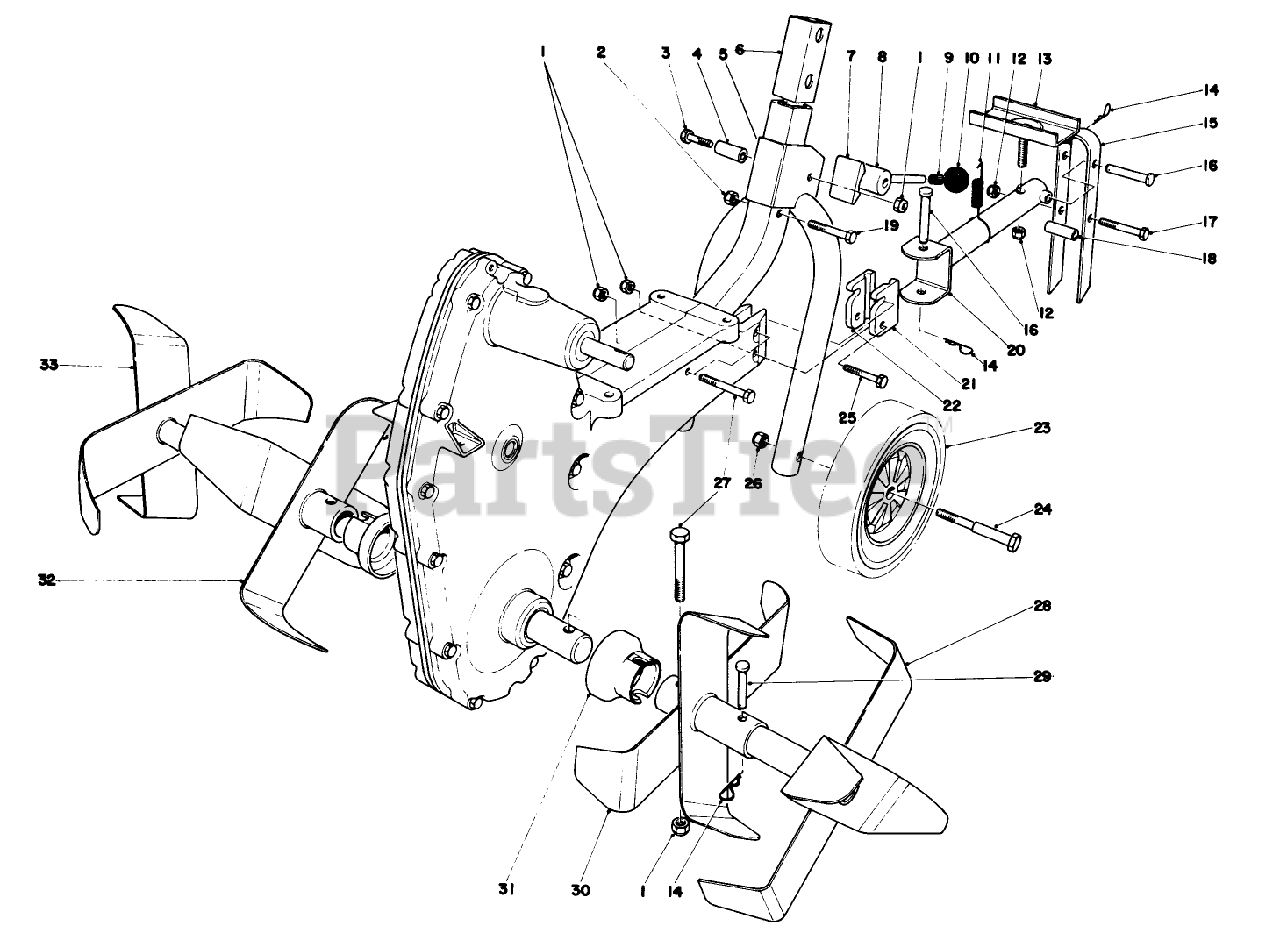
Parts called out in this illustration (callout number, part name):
1	NUT-HEX, SIDE DEFORM
2	NUT-HEX, SIDE DEFORM
3	SCREW-HH
4	CAM SPACER
12	NUT-LOCK, SIDE
14	PIN-COTTER
16	PIN-CLEVIS
17	SCREW-HH
19	SCREW-HH
23	WHEEL TIRE ASM 8 IN
25	SCREW-HH
26	NUT-LOCK, CONE
27	SCREW-HH
29	PIN-CLEVIS
